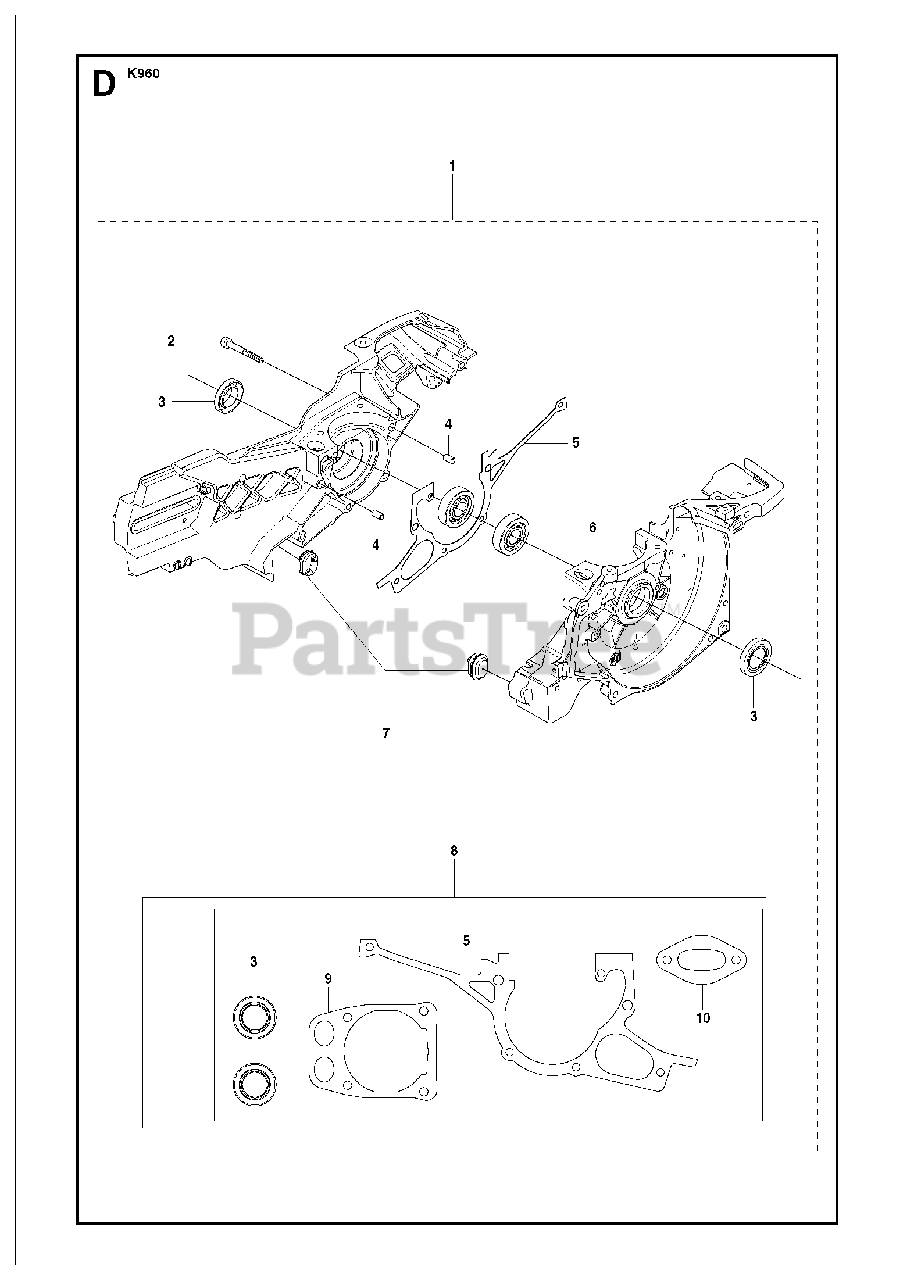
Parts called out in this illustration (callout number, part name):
1	CRANKCASE ASSYIncl. 2 - 8
2	SCREW ITXSCM
3	SEALING RING
4	GUIDE BUSHING
6	BALL BEARING
7	RUBBER BUSHING
8	GASKET KITIncl. 3, 5, 9, 10
9	GASKET
10	GASKET
